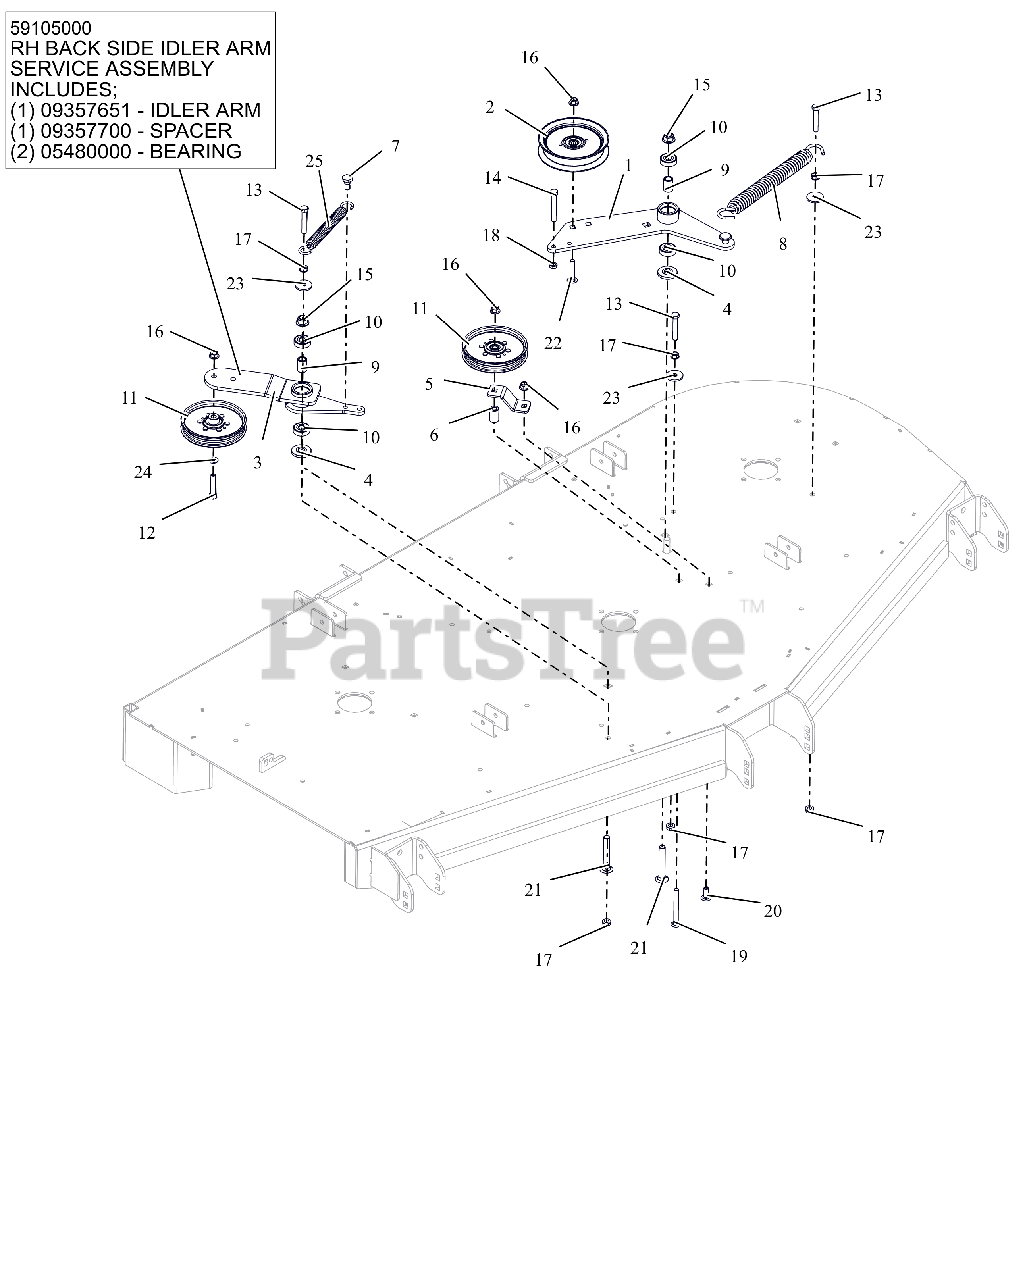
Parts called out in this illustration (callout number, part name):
1	DECK PTO IDLER ARM WLDMT - BLK
2	IDLER, FLAT 5.00"
3	DECK RH IDLER ARM WMT - BLK
3	RH BACKSIDE IDLER ARM ASSEMBLY
4	SPACER, IDLER ARM
5	PTO FIXED IDLER MTG BRKT -RED
6	BUSHING, SLV .380X.750X1.190
7	BLT,SHLDR EP .38-16X.30 HEX YZ
8	SPRING, EXTENSION
9	SPACER .510 X .75 X 1.1485
10	BRG-BALL .500X1.38X.437
11	PULLEY, FLAT IDLER
12	BLT,HEX .38-16X2.00 G5 ZCC
13	BLT,HEX .38-16X2.25 G5 ZCC
14	BLT, HEX .38-16X2.75 G5 ZCC
15	NUT,NYL-FLG .50-13 GF ZCC
16	NUT,NYL-FLG .38-16 GF ZCC
17	NUT, SPNLK-FLG .38-16 G5 ZCC
18	NUT-JAM .375-16 G2 ZCC
19	BLT,RHSSN .38-16X3.50 G5 ZCC
20	BLT,RHSSN .38-16X1.00 G5 ZCC
21	BTL,RHSSN .500-13 X 3.25 G5 ZCC
22	BLT,RHSSN.375-16X2.00 G5 ZCC
23	WSHR,FLT .406X1.375X.135 ZCC
24	WSHR,FLT .406X.812X.065 ZCC
25	SPRING, EXTENSION
